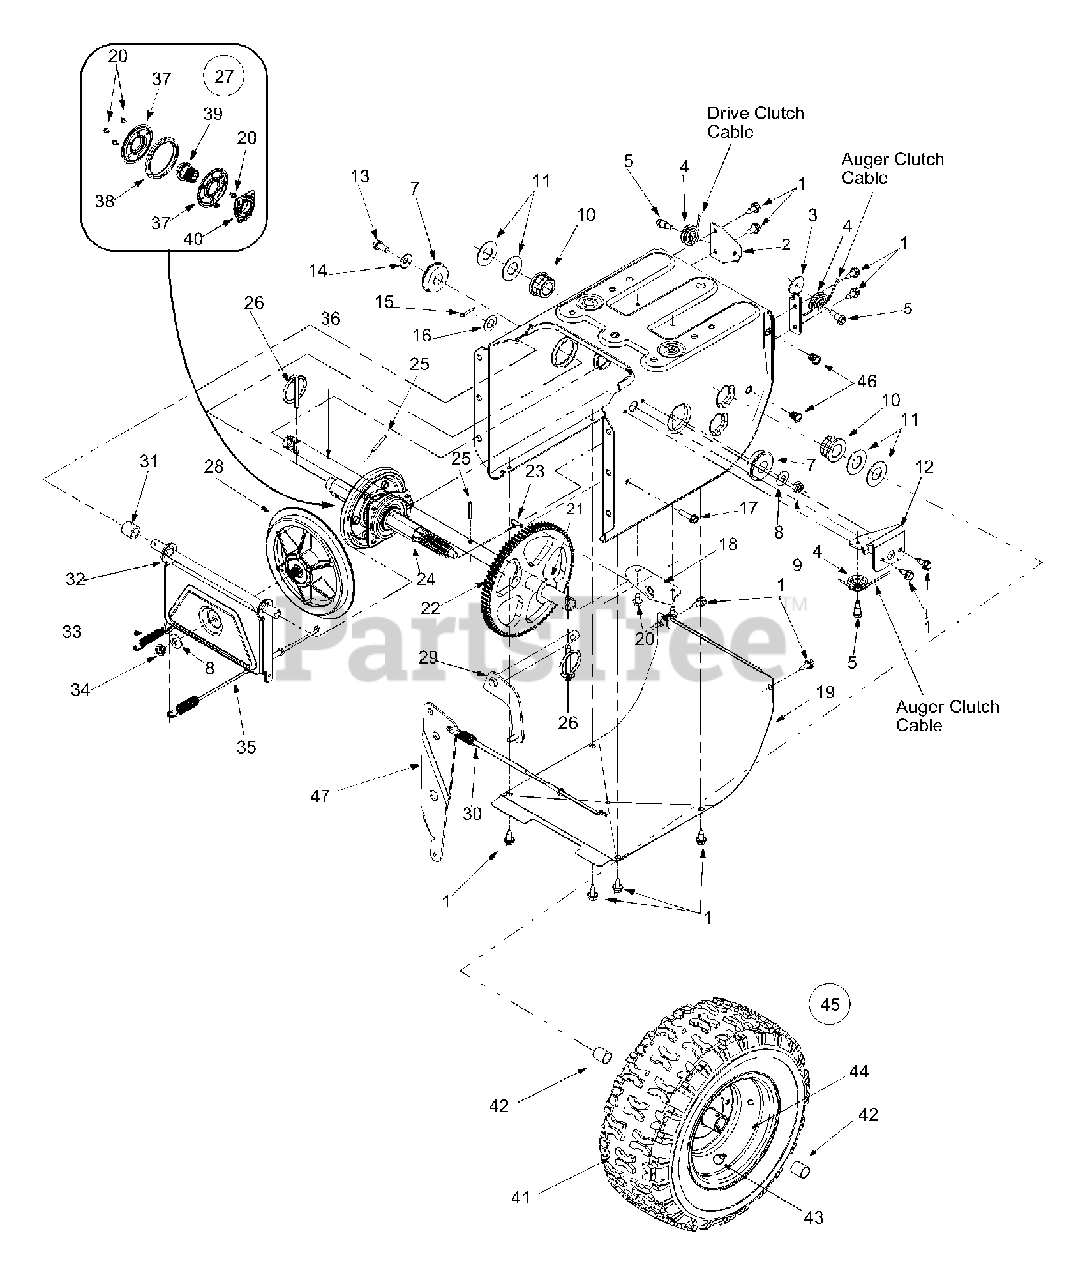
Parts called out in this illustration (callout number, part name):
1	Hex Screw
5	Hex Screw 1/4-28
8	Bell Washer
9	Lock Jam Nut
10	Hex Flange Bearing
11	Flat Washer
14	Bell Washer .340 ID x .872 OD
15	Cotter Pin
16	Flat Washer .536 ID x .930 OD
17	Hex Washer Screw 1/4-20
21	Flat Washer .760 ID x .50 OD
24	7-Tooth Shaft
25	Roll Pin
26	Clik Pin
27	Friction Wheel Assembly
28	Friction Disc Wheel
29	Wheel Shift Rod Assembly
30	Drive Cable
31	Spacer
34	Jam Nut, 3/8-24
35	Drive Cable
39	7-Tooth Shaft
40	Friction Wheel Bearing
41	Tire Only, 16 x 6.5 x 8
42	Sleeve Bearing
43	Air Valve
